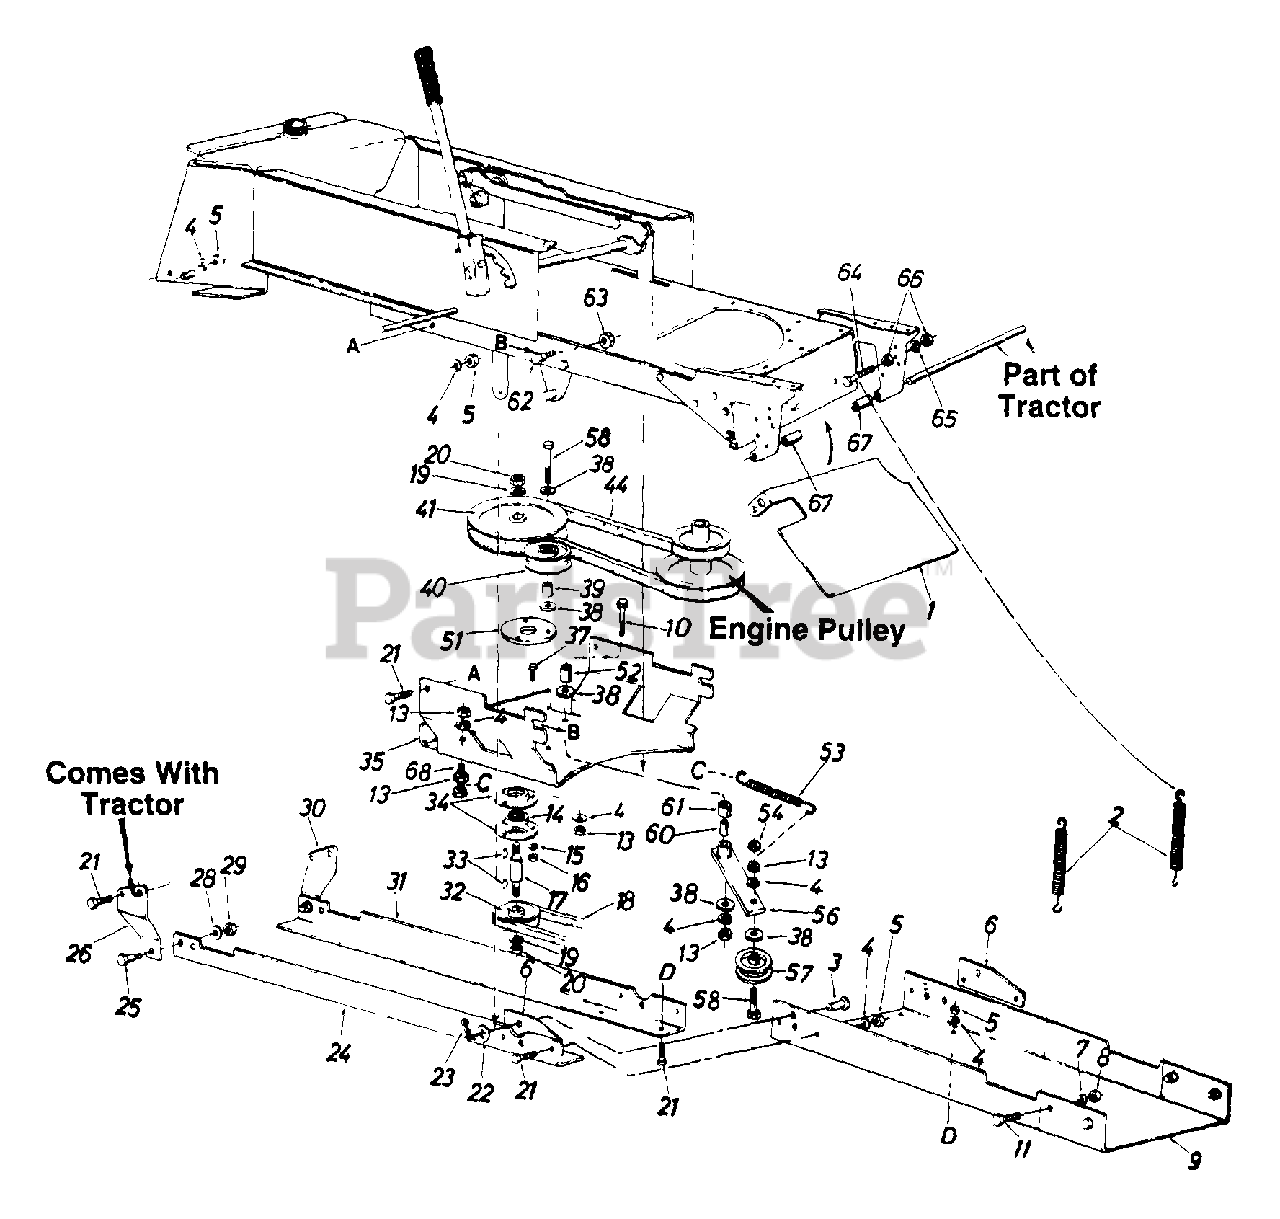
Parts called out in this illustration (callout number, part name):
3	Clevis Pin
4	L-Wash. 3/8" I.D.
5	Hex L-Nut 3/8-24 Thd.
6	Attaching Plate
7	L-Wash. 1/2" I.D.
8	Hex L-Nut 1/2-20 Thd.
11	Hex Bolt 1/2-20 x 1.25" Lg.
13	Hex Jam Nut 3/8-16 Thd.
14	Ball Bearing
15	L-Wash. 5/16" I.D.
16	Hex Nut 5/16-18 Thd.
17	Spindle
18	"V"-Belt
19	L-Wash. 5/8" I.D.
20	Hex Jam Nut 5/8-11 Thd.
21	Hex Bolt 3/8-24 x 1.00" Lg.
22	Flat Washer
23	Internal Cotter Pin
29	Hex Nut 7/16-14 Thd.
33	#6 Hi-Pro Key 3/16 x 5/8" Dia.
34	Bearing Housing
35	Supporting Bracket
37	Hex Sems Bolt 5/16-18 x 1"
38	Fl-Wash. 38" I.D. x 1" O.D.
39	Spacer .38" I.D. x .62" O.D.
40	Fl-Idler Pulley
41	Upper Drive Pulley
44	"V"-Belt
53	Extension Spring 4.75" Lg.
54	Hex L-Nut 3/8-16 Thd.
56	Idle Arm Ass'y.
57	Idler Pulley
58	Hex Bolt 3/8-16 x 2.25" Lg.
60	Spacer .377" I.D. x.83" Lg.
61	Spacer .38" I.D. x 565" Lg.
62	Shoulder Bolt .498" Dia.
63	Hex L-Nut 3/8-16 Thd.
64	Hex Bolt 1/4-28 x 1.50" Lg.
65	L-Wash. 1/4" I.D.
66	Hex Nut 1/4-28 Thd.
67	Spacer 63" I.D. x 1.75" Lg.
68	Hex Bolt 3/8-16 x 2" Lg.
